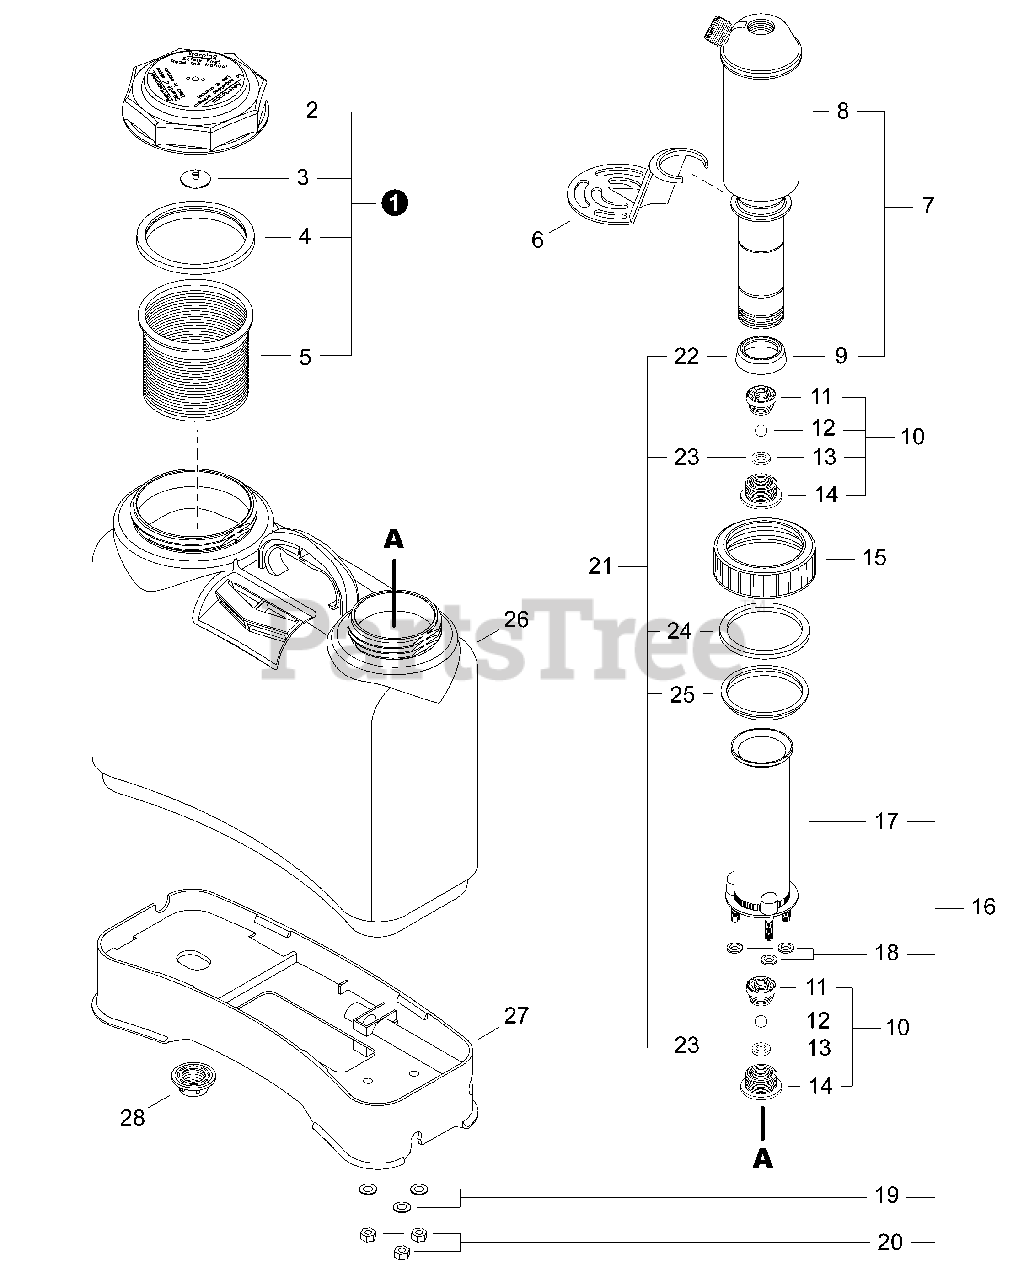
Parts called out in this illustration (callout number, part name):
1	CAP KIT, TANK
2	CAP, TANK
3	VALVE, CHECK - CAP
4	GASKET, BASKET
5	BASKET, FILTER
6	AGITATOR
7	CHAMBER KIT, PRESSURE
8	CHAMBER, PRESSURE
9	CUP, PLUNGER
10	VALVE ASSY, CHECK
11	BODY, VALVE
12	BALL, VALVE
13	WASHER
15	RING, LOCKING
16	CYLINDER KIT, PISTON
17	CYLINDER, PISTON
18	GASKET, STUD
19	WASHER
21	GASKET KIT, PUMP
22	CUP, PLUNGER
23	WASHER
24	WASHER, FELT
25	GASKET, CHAMBER
26	TANK, SPRAYER
27	BASE, TANK
28	NUT, TANK
